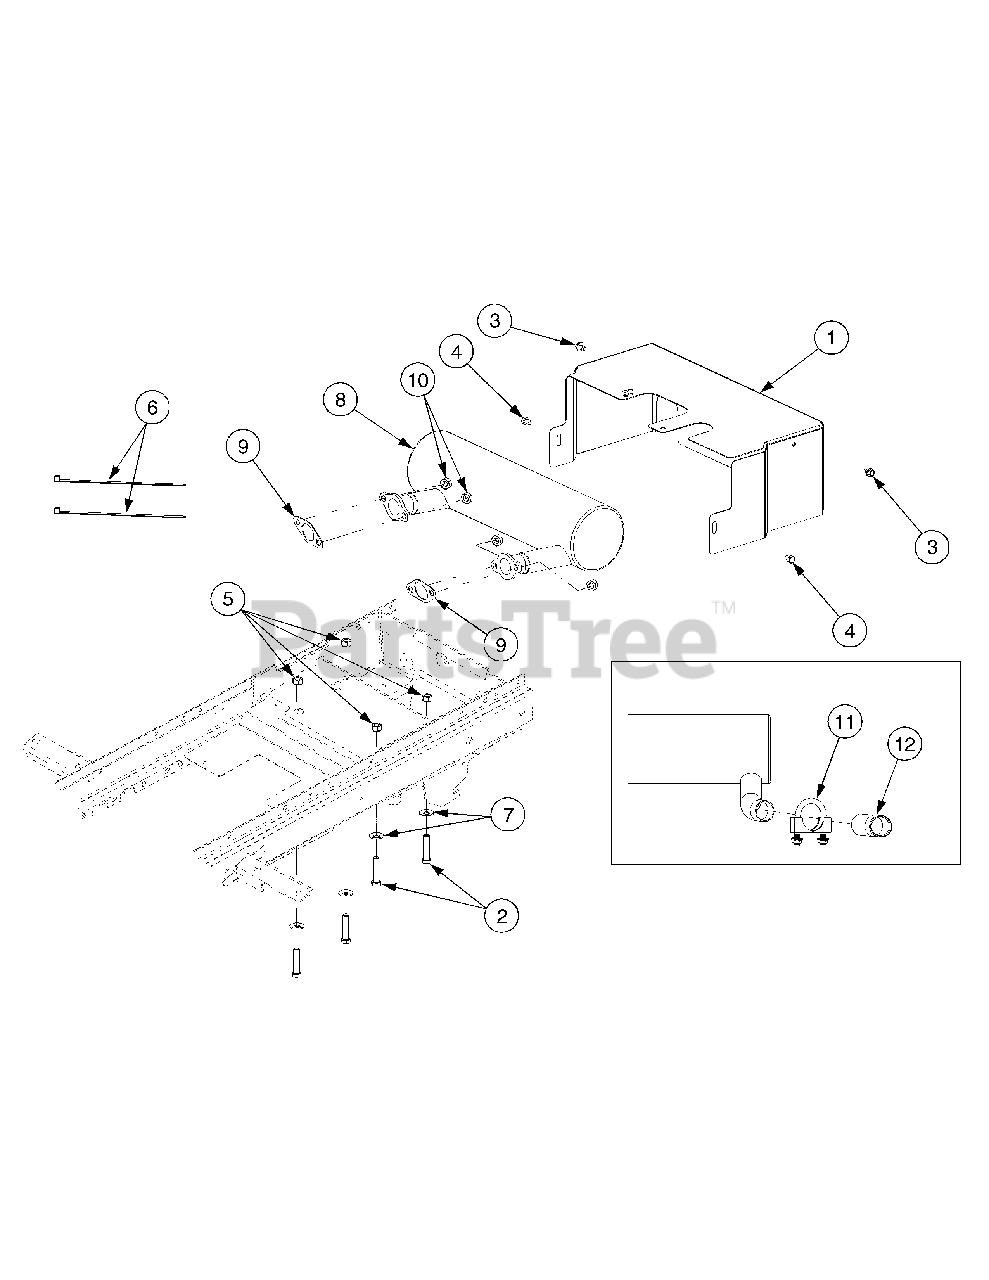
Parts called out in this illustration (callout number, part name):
1	Shield, Heat
2	Bolt, Eng Mount, 3/8-24 x 1.75 GR5
3	Screw, Hx Wsh Hd Tapp, 1/4-20 x .375
4	Screw, Hex Cap, M6 x 1 x 10
5	Nut, Hex Lock, 3/8-24
6	Tie, Cable
7	Washer, Bell, .380 x .88 x .062
8	Muffler Assembly
9	Gasket, Exhaust
10	Nut, Hex Flange
11	Clamp, Muffler
12	Pipe Extension, Exhaust
